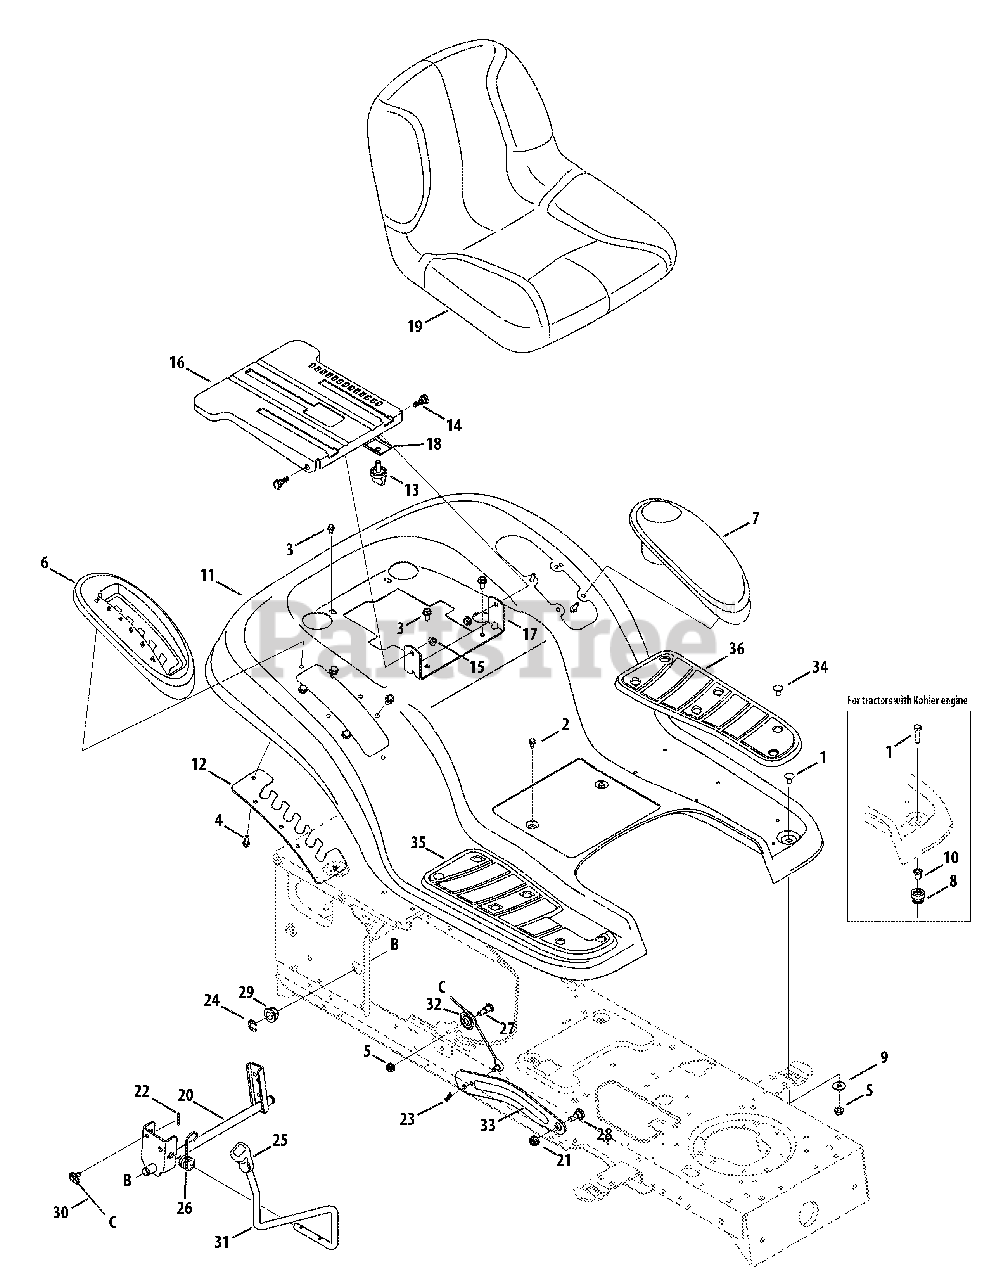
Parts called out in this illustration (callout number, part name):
1	Hex Screw, 5/16-18 x 1.25 (Sngle. Cyl.)
1	Carriage Bolt, 5/16-18 (Twin Cyl. Models)
2	Screw, 1/4-20, 0.500
3	Screw, 5/16-18, 0.750x
4	Screw, 1/4-15, 0.750
5	Nut, Flange Lock, 5/16-18, GrF
6	Deck Lift Lever Cover
7	Cover with Cup Holder
8	Grommet, .4375 x .750 (Sngle. Cyl.)
9	Washer, Flat,.344 x 1.0 x.063
10	Flanged Spacer (Sngle. Cyl. Models only)
11	Hydro Fender, 4-style
12	Deck Lift Plate
13	Knob, 3/8-16
14	Screw, Shoulder,.437 x.268
15	Flange Lock Nut, 5/16-18
16	Seat Mount Bracket
17	Seat Pivot Bracket
18	Seat Knob Adjust Bracket
19	High Back Seat
20	Deck Lift Shaft Assembly
21	Nut, Flange Lock, 3/8-16, GrF
22	Pin, Cotter,.072 Dia. x 1.13
23	Pin, Cotter, 3/32, 1.0
24	Ring, E Type,.625 Dia.
25	Grip, Handle, 1/2
26	Spring, Torsion
27	Screw, 5/16-18 x.620 Gr2
28	Scr.,Shldr, .625 x.165,(42" Deck)
28	Scr.,Shldr, .500 x.270, (50" Deck)
29	Bearing, Hex Flange
30	Cable, Lift, 16.16
31	Handle, Lift
32	Pulley, Roller
33	Arm, Lift - RH (42" Deck)
33	Arm, Lift - LH (42" Deck)
33	Arm, Lift - Universal (50" Deck)
34	Ratchet Clip
35	RH Foot Pad
36	LH Foot Pad
